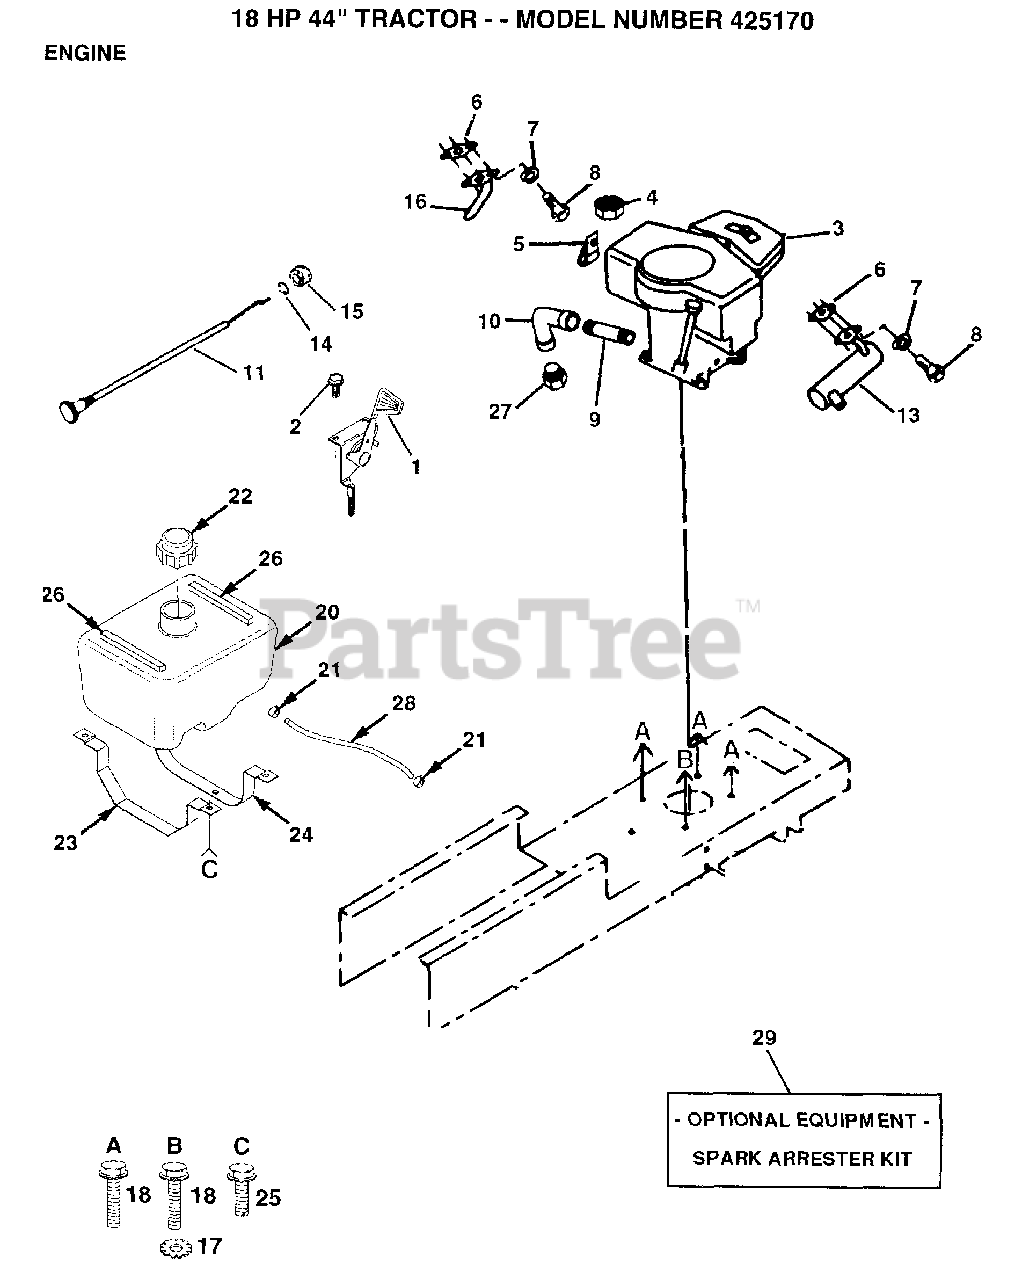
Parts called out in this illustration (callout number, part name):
2	SCREW LT
3	ENGINE B&S 18HP
4	NUT
5	CLIP T
7	LOCKWASHER
9	PIPE NIPPLE LT
10	ELBOW
11	CHOKE CONTROL
14	LOCKWASHER
16	EXHAUST TUBE T
17	LOCKWASHER
18	SCREW LT
20	TANK FUEL 1.9 NAT
21	HOSE CLAMP
22	CAP ASM FUEL
23	STRAP TANK FUEL
24	STRAP TANK FRONT
25	SCREW
26	"STRIP,FORM"
28	HOSE T
